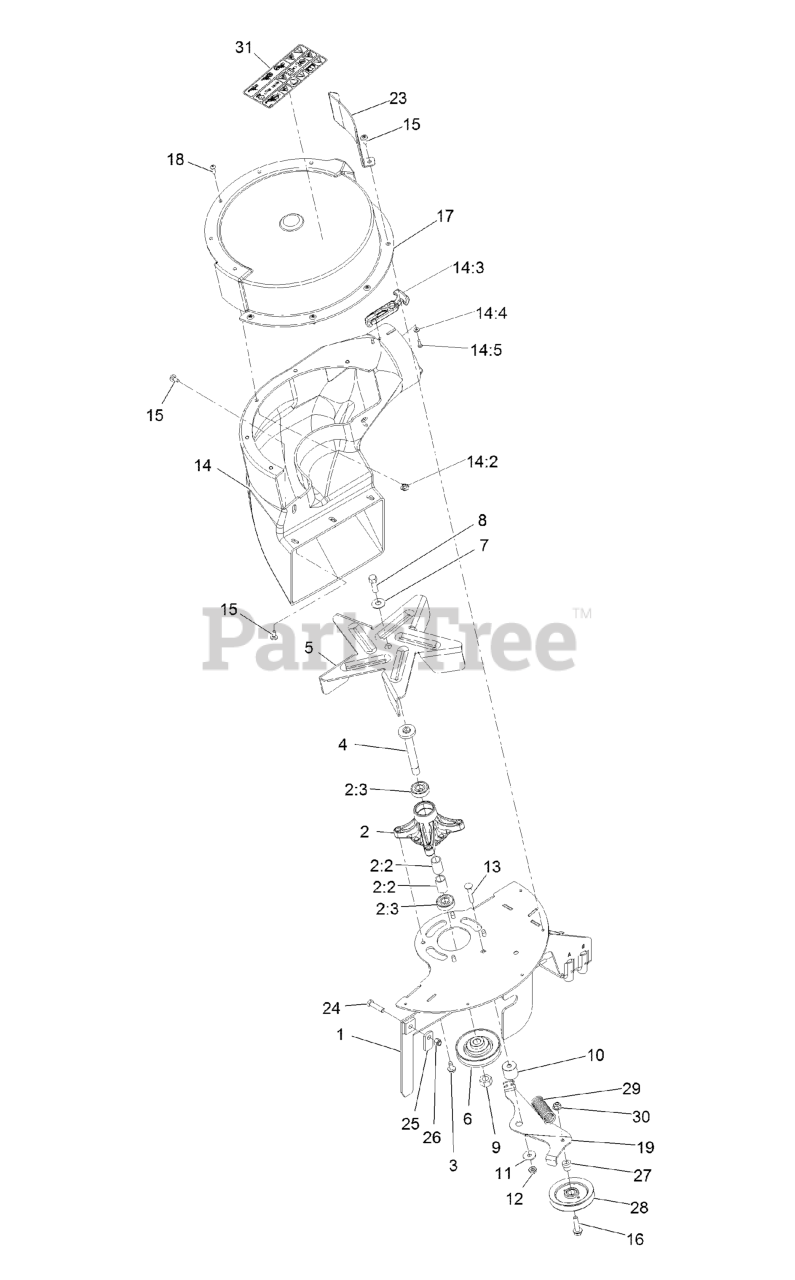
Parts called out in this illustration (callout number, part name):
1	WELDMENT-SUPPORT, BLOWER
2	SPINDLE ASM
2:3	BEARING-BALL
3	Screw-HWH 5/16-18 X 3/4 Tf
4	Shaft - Spindle
5	Fan-Blower
6	SHEAVE-BLOWER OFFSET
7	WASHER-BELLEVILLE
8	Screw-HH
9	Nut-Hex
10	SPACER-STEPPED
11	WASHER-PIVOT
12	NUT-HF, NI
13	SCREW-CARR
14	ASM-Blower Chute, Plastic
14:2	Insert-T-Nut
14:3	LATCH-RUBBER
14:4	WASHER-FLAT
14:5	SCREW-PPH
15	SCREW-SHOULDER
16	SCREW-HHF
17	ASM-BLOWER COVER
18	SCREW-PRH
19	ARM-IDLER, BLOWER
23	Guard-Blower
24	SCREW-HH
25	LATCH-CATCHER, GRASS
26	NUT-LOCK, NI
27	HUB,SPACER
29	SPRING-IDLER
30	NUT-HF, NI
31	DECAL-WARNING BLOWER W/RO
